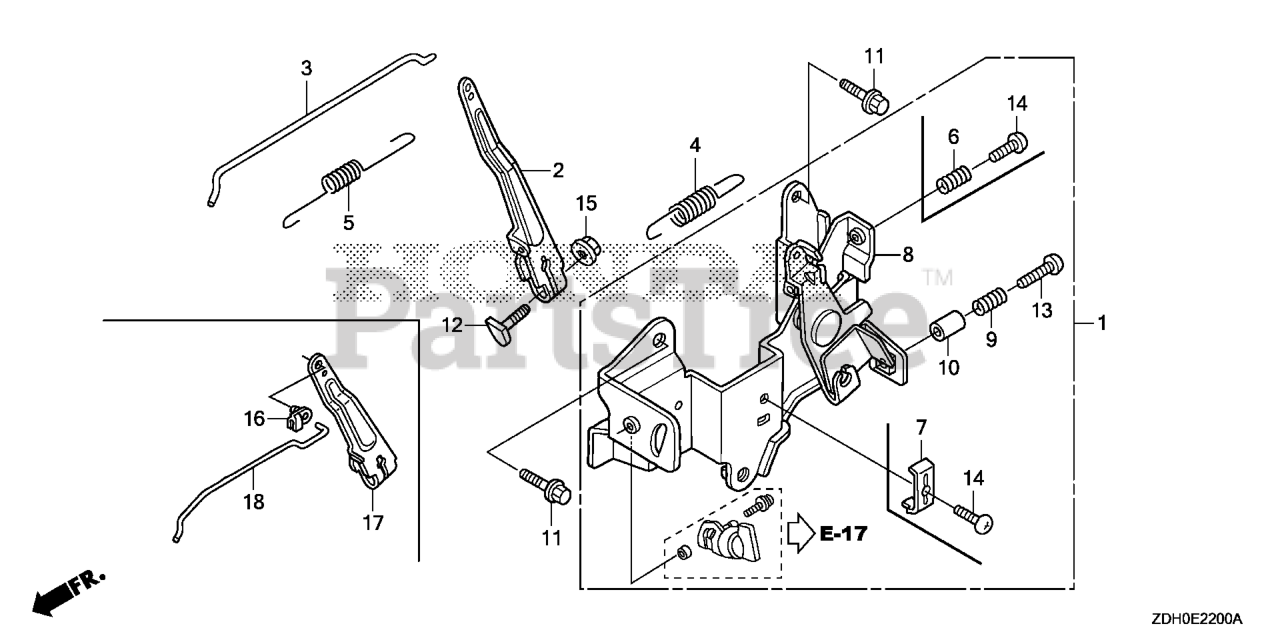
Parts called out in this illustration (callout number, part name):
1	CONTROL ASSY.
4	SPRING, GOVERNOR
5	SPRING, THROTTLE RETURN
8	BASE, CONTROL
9	SPRING, CONTROL ADJUSTING Use from Engine SN 2327377.
10	COLLAR, STOPPER
11	BOLT, FLANGE (5X12)
12	BOLT, GOVERNOR ARM
13	SCREW, RECESSED (5X28)
15	NUT, FLANGE (6MM)
16	JOINT, ROD
17	ARM, GOVERNOR
18	ROD, GOVERNOR
